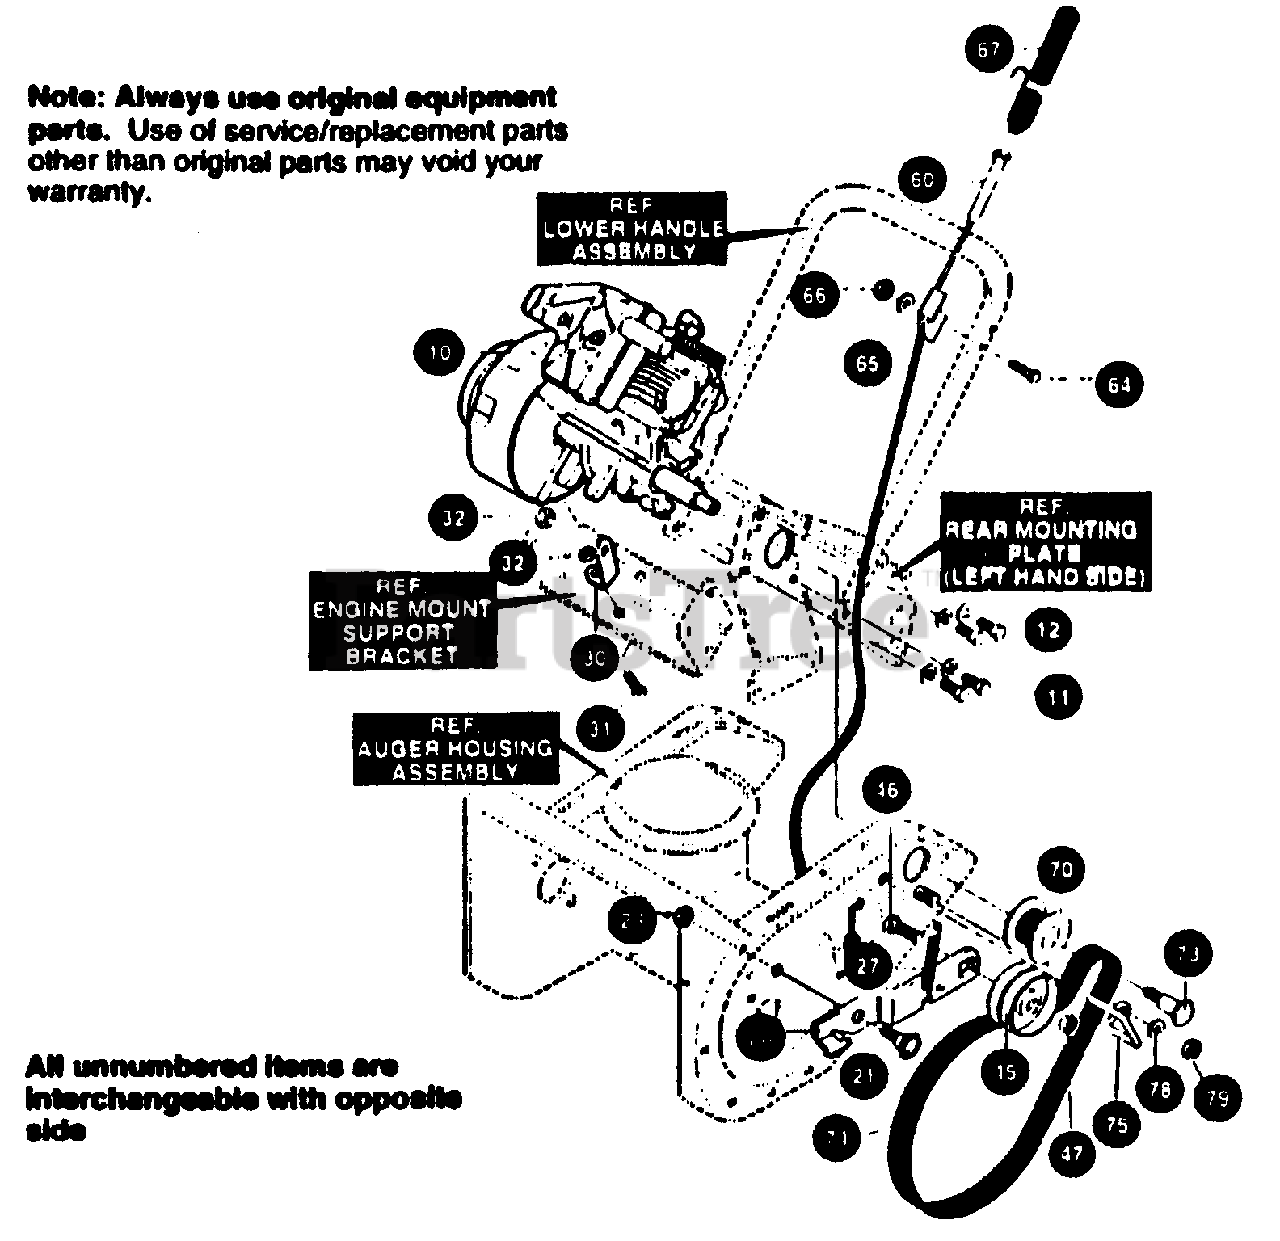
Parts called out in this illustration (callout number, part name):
11	SCREW, 5/16-18X .75
12	WASHER, HVSPTLK .328X.60X.09
20	BRKT, IDLER ARM
21	BOLT, 5/16-18
27	SPRING, IDLER BRAKE
29	NUT, 5/16-18 REGHEXCTRLK
30	SUPPORT, ENGINE
31	SCREW, 5/16-18X .50
32	NUT, 5/16-18 REGHEXCTRLK
45	PULLEY, IDLER
46	BOLT, 3/8-16X1.50
47	NUT, 3/8-16 HXCTRLKJAM
60	CABLE, DRIVE CONTROL
64	SCREW, 1/4-20X1.50
65	WASHER, FLAT .281X .63X.065
66	NUT, 1/4-20 REGHEXCTRLK
67	COVER, CABLE SPRING
70	PULLEY, 10-RIB POLY-V
73	BOLT, SHOULDER .625 X .282
74	BELT, 10 RIB POLY-V
75	GUIDE, BELT
78	WASHER, FLAT .312X .73X.065
79	NUT, 5/16-18 REGHEXCTRLK
